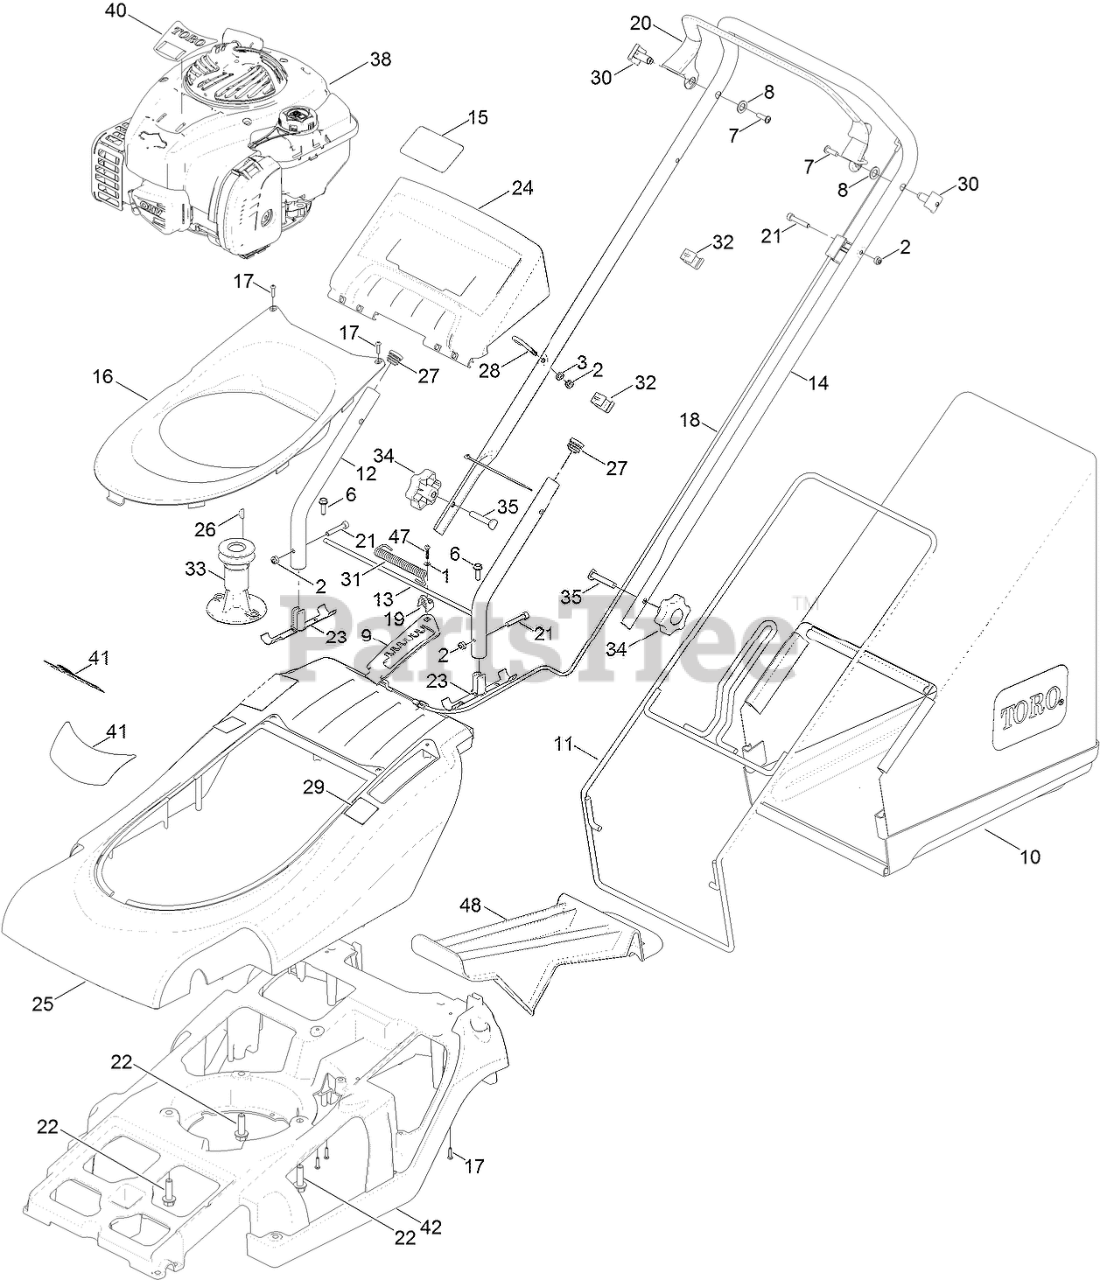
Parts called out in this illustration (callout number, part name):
1	WASHER
2	NUT-NYLOC
3	WASHER-PLAIN
6	SCREW-TAPTITE
7	SCREW
8	WASHER-NYLON
9	PLATE-HOC
10	GRASSBAG
11	FRAME-GRASSBAG
12	HANDLEBARS-LOWER
13	BAR-HINGE
14	HANDLEBARS
15	DECAL-SAFETY
16	MOULDING-TRIM
18	CABLE-BRAKE, ENGINE
19	CLIP-P
20	BAILARM
21	SCREW-SOCKET
22	SCREW-TAPTITE, UNC
23	PLUG-HANDLEBAR
24	MOULDING-DEFLECTOR, REAR
25	TOP-COVER
26	KEY-WOODRUFF
27	PLUG-TUBE
28	GUIDE-ROPE
29	DECAL-HOC
30	PIN-PIVOT
31	SPRING-DEFLECTOR
32	GUIDE-CABLE
33	CARRIER-BLADE
34	KNOB-HANDLEBAR
35	BOLT-HANDLEBAR
40	DECAL-ENGINE
41	DECAL-RECYCLE
47	SCREW-PLASTITE
48	PLUG-MULCHING
